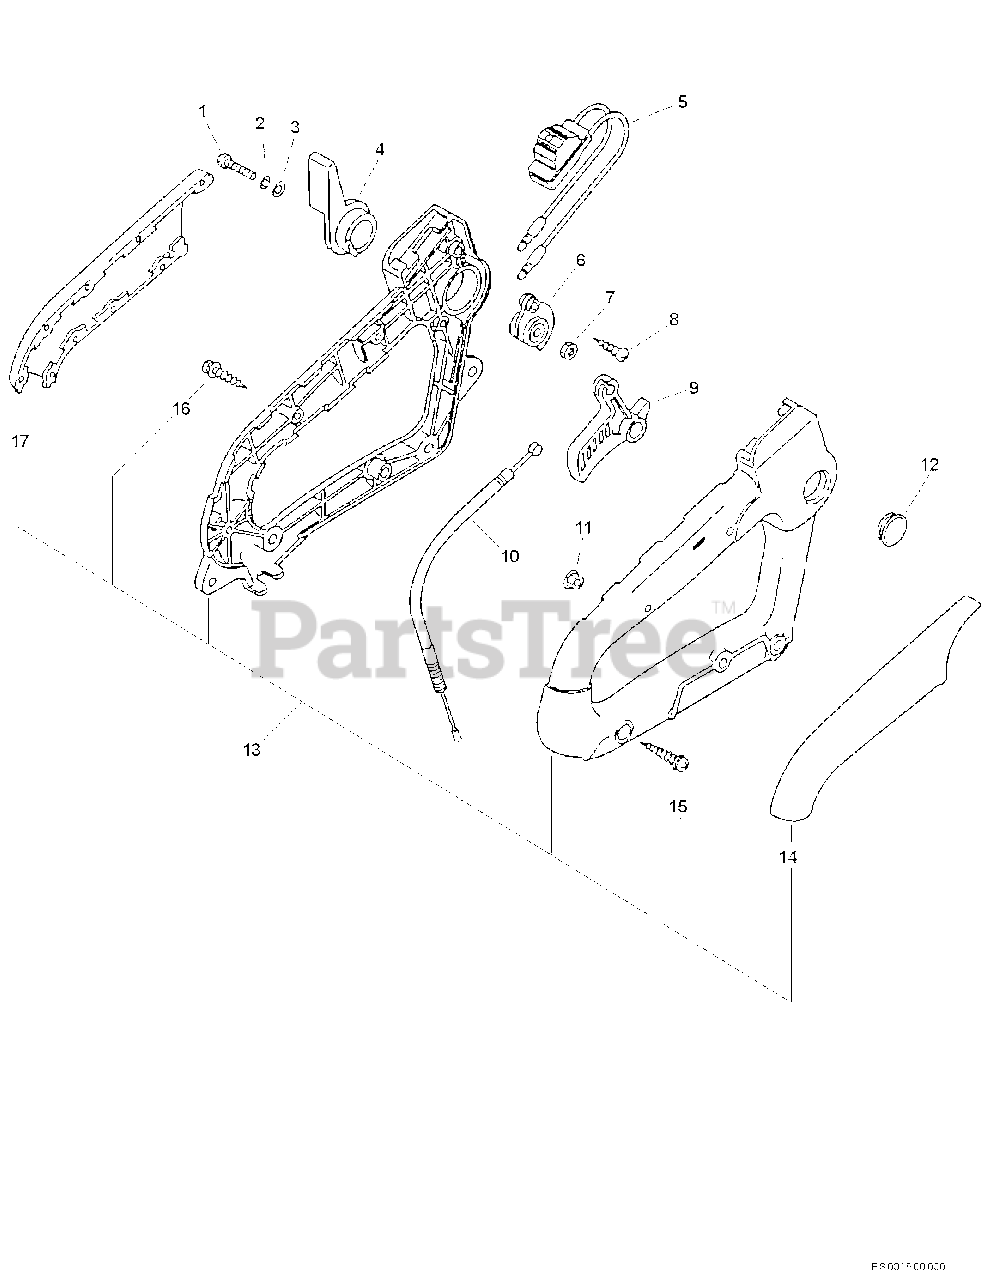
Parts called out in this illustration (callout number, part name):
1	SCREW 6×20
2	WASHER, SPRING 6
3	WASHER 6.5×13×1
4	CONTROL, THROTTLE
5	SWITCH, ON-OFF
6	BRACKET, THROTTLE
7	NUT, HEX M6
8	SCREW 4×10
9	TRIGGER, THROTTLE
10	CABLE, THROTTLE
11	NUT, FLANGE M5
13	HANDLE KIT
14	GRIP, RIGHT
15	SCREW 5×30
16	SCREW 4×22
17	GRIP, LEFT
